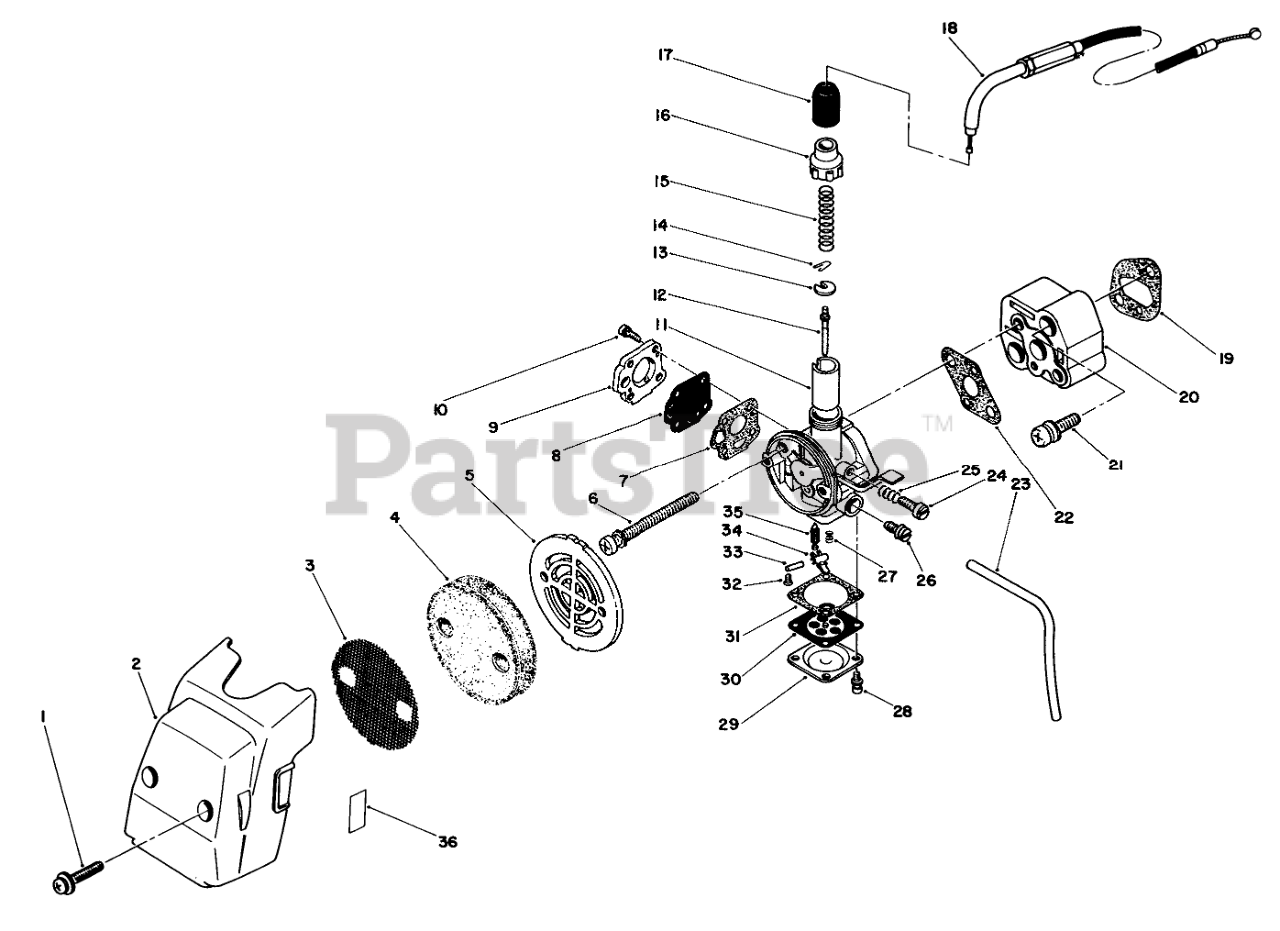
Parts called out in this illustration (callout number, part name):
1	SCREW & WASHER
2	CLEANER CASE
3	SCREEN
4	ELEMENT
6	SCREW W/ WASHER
7	PUMP COVER GASKET
8	PUMP DIAPHRAGM
9	Pump Cover Assembly
10	SCREW W/ WASHER
11	THROTTLE VALVE
12	NEEDLE JET
13	SPRING RETAINER
14	NEEDLE CUP
15	SPRING
17	AIR SEAL
18	THROTTLE WIRE
19	INSULATOR GASKET
20	INSULATOR
21	SCREW & WASHER
22	CARB GASKET
23	FUEL TUBE
24	Screw-Adjusting
25	ADJ. SCREW SPRING
26	Needle-Main Jet
27	VALVE SPRING
28	SCREW W/ WASHER
29	DIAPHRAGM COVER
30	MAIN DIAPHRAGM
31	DIAPHRAGM GASKET
32	FLOAT SCREW
33	FLOAT PIN
34	FLOAT ARM
35	FLOAT VALVE
36	CHOKE LABEL
